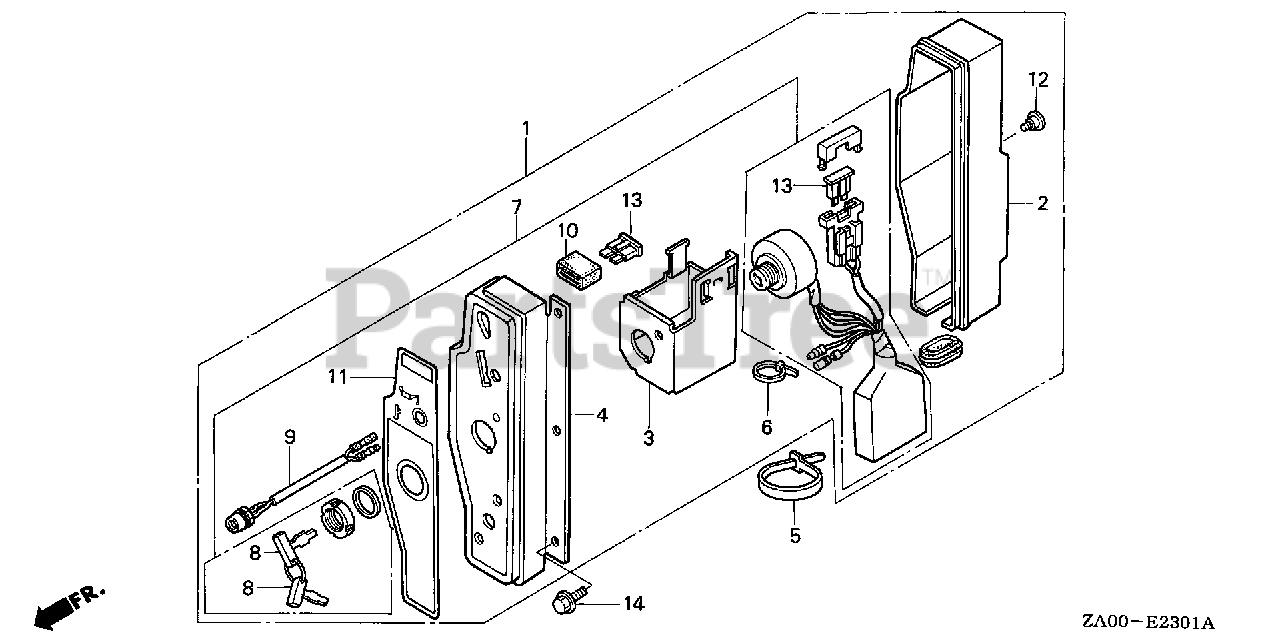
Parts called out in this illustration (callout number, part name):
1	BOX ASSY., CONTROL (10A)
2	CASE, CONTROL
3	BRACKET, CASE MOUNTING
4	PANEL ASSY., CONTROL
5	BAND, WIRE
7	SWITCH ASSY., COMBINATION (10A)
8	KEY (HONDALOCK)
9	LED ASSY. (RED)
10	SUSPENSION, TURN SIGNAL RELAY (DENSO)
11	PLATE, CONTROL INDICATION (10A)
12	SCREW, SPECIAL (6X12)
13	FUSE, BLADE (15A)
14	BOLT, FLANGE (6X8)
